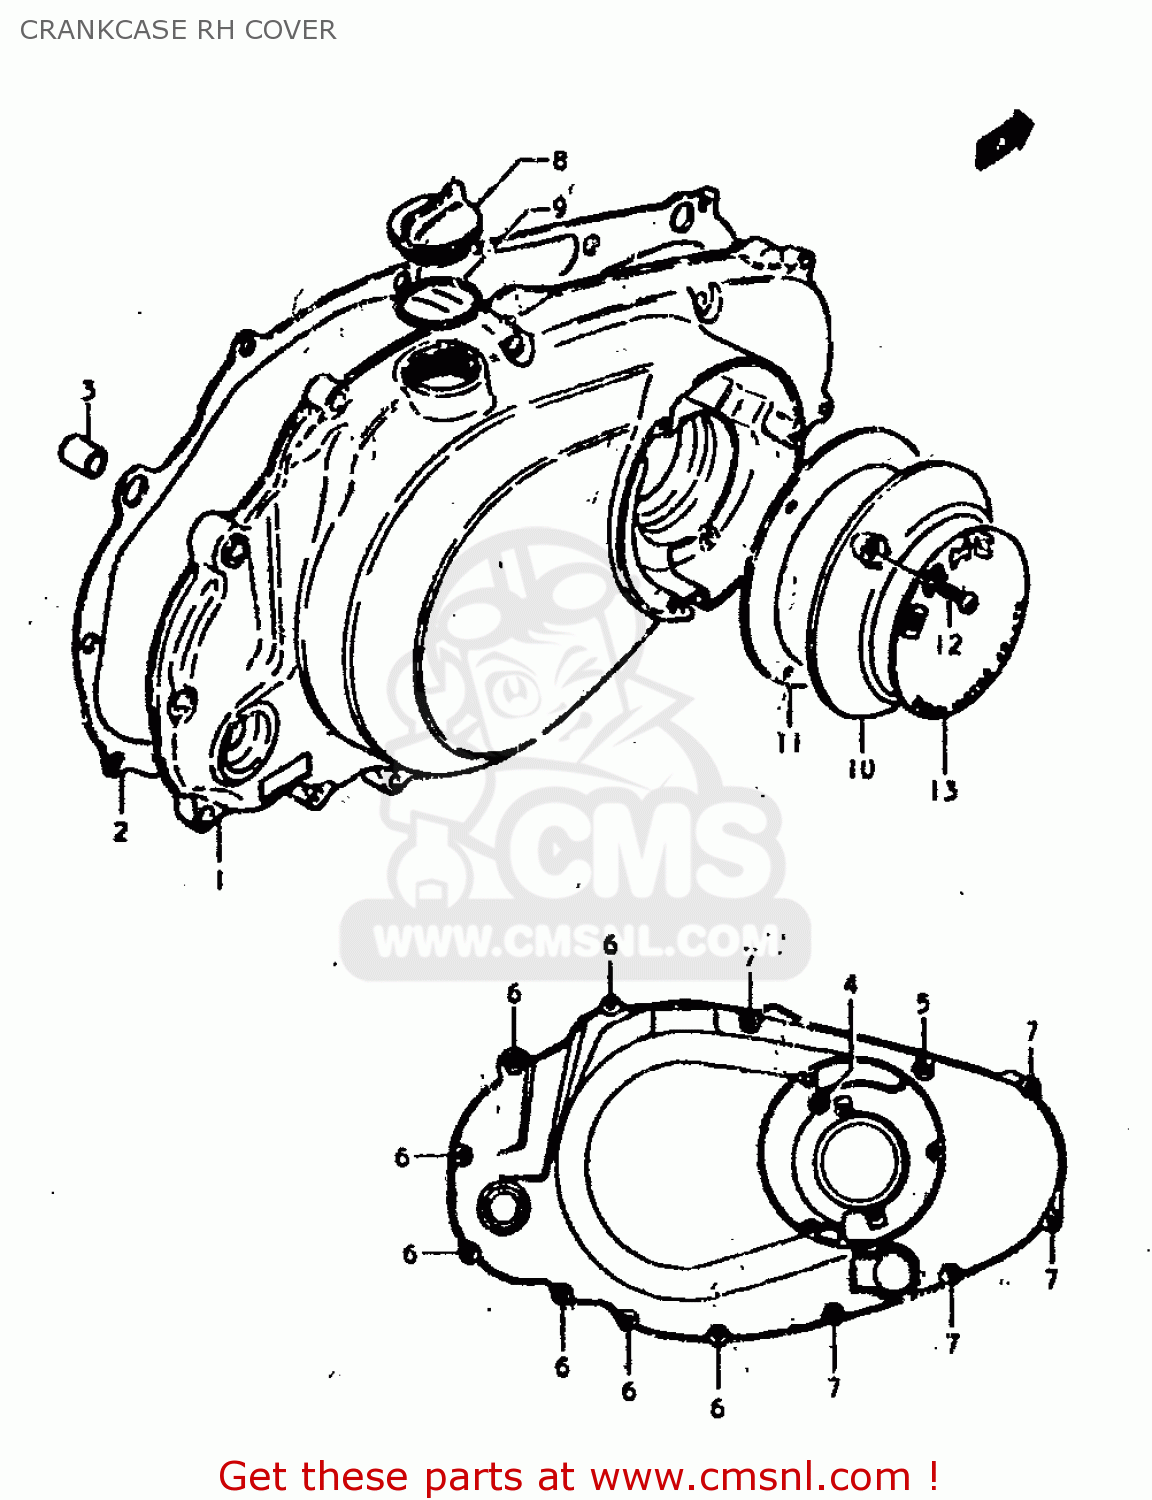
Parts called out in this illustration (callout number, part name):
1	COVER,CLUTCH
2	GASKET,CLUTCH COVER (MCA)
3	PIN
4	SCREW 6X60
5	SCREW (6X45)
6	SCREW (6X35)
7	SCREW
8	CAP
9	O RING(D:2.2,ID:32)
10	COVER,CONTACT BREAKER
11	GASKET,CONTACT BREAKER (MCA)
12	SCREW 5X20
13	EMBLEM
